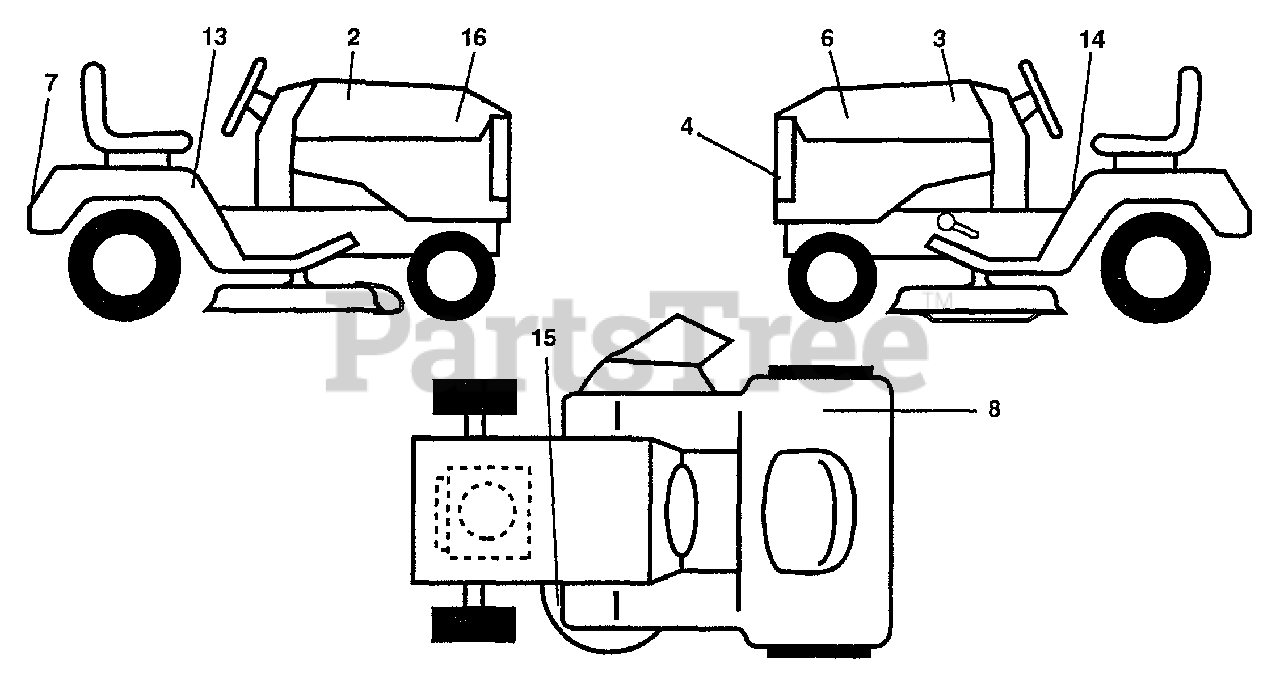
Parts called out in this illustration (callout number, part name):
2	Decal, Stripe, Hood, R.H.
3	Decal, Stripe, Hood, L.H.
4	Decal, Grill
6	Decal, Insert Hood, R.H.
7	Decal, Logo, Fender
8	Decal, Dba
13	Decal, Caution (English)
14	Decal, Inst. Oper. Fender
15	Decal, V-Belt Sch. 36" LR
16	Decal, Insert Hood, L.H.
